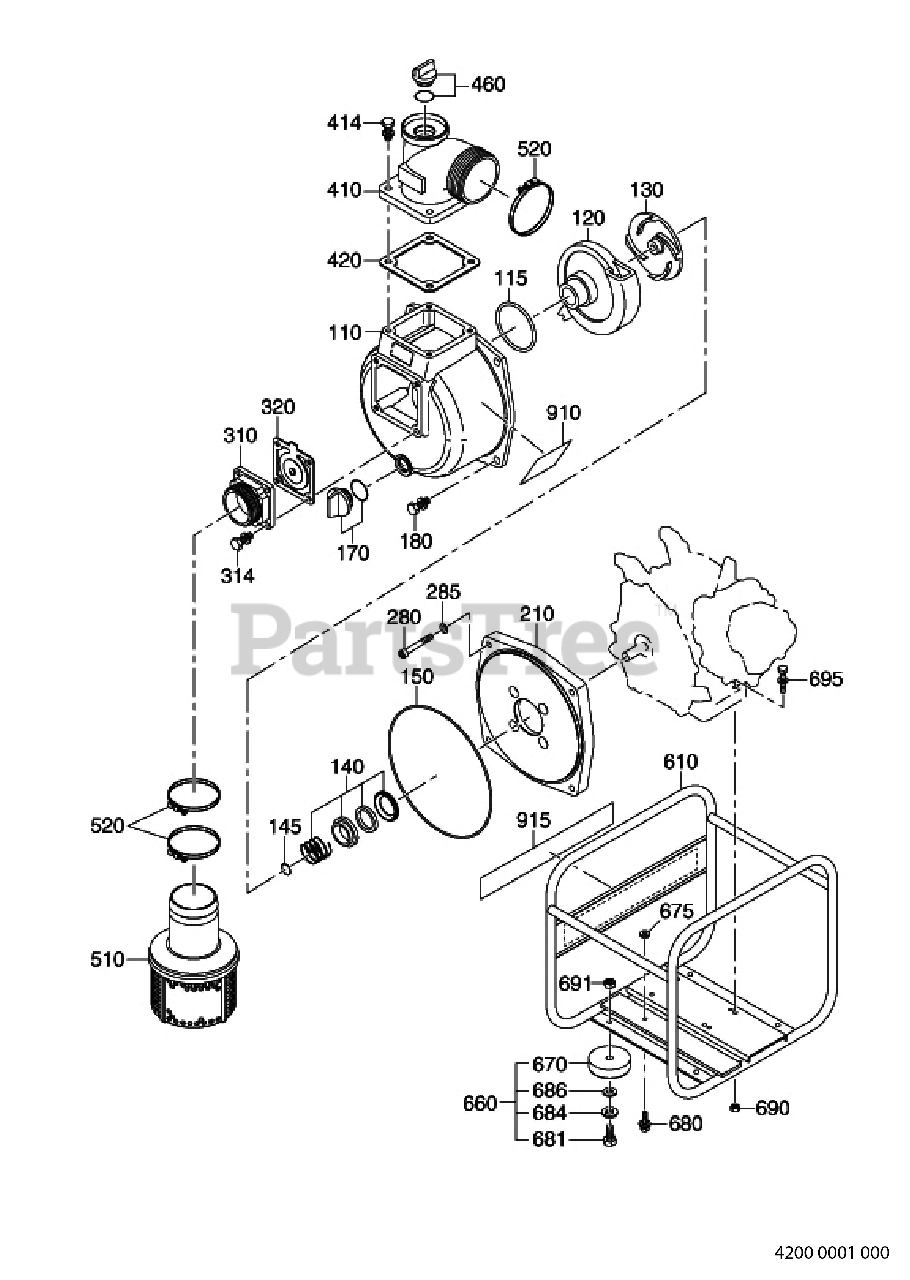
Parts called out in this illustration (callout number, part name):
140	MECHANICAL SEAL
145	ADJUSTING WASHER
180	BOLT & WASHER AY
210	FLANGE BRACKET
280	SOCKET BOLT
285	SEAL WASHER
310	SUCTION OR DELIVERY
314	BOLT & WASHER AY
410	DELIVERY FLANGE
414	BOLT & WASHER AY
420	DELIVERY FLANGE PACK
520	HOSE BAND
610	BASE AY
660	CUSHION RUBBER SET
670	CUSHION RUBBER
675	CUSHION RUBBER
680	BOLT AND WASHER AY
681	BOLT & WASHER AY
684	SPRING WASHER
686	WASHER
910	LABEL,PUMP NAME
915	LABEL(TRADE MARK)
